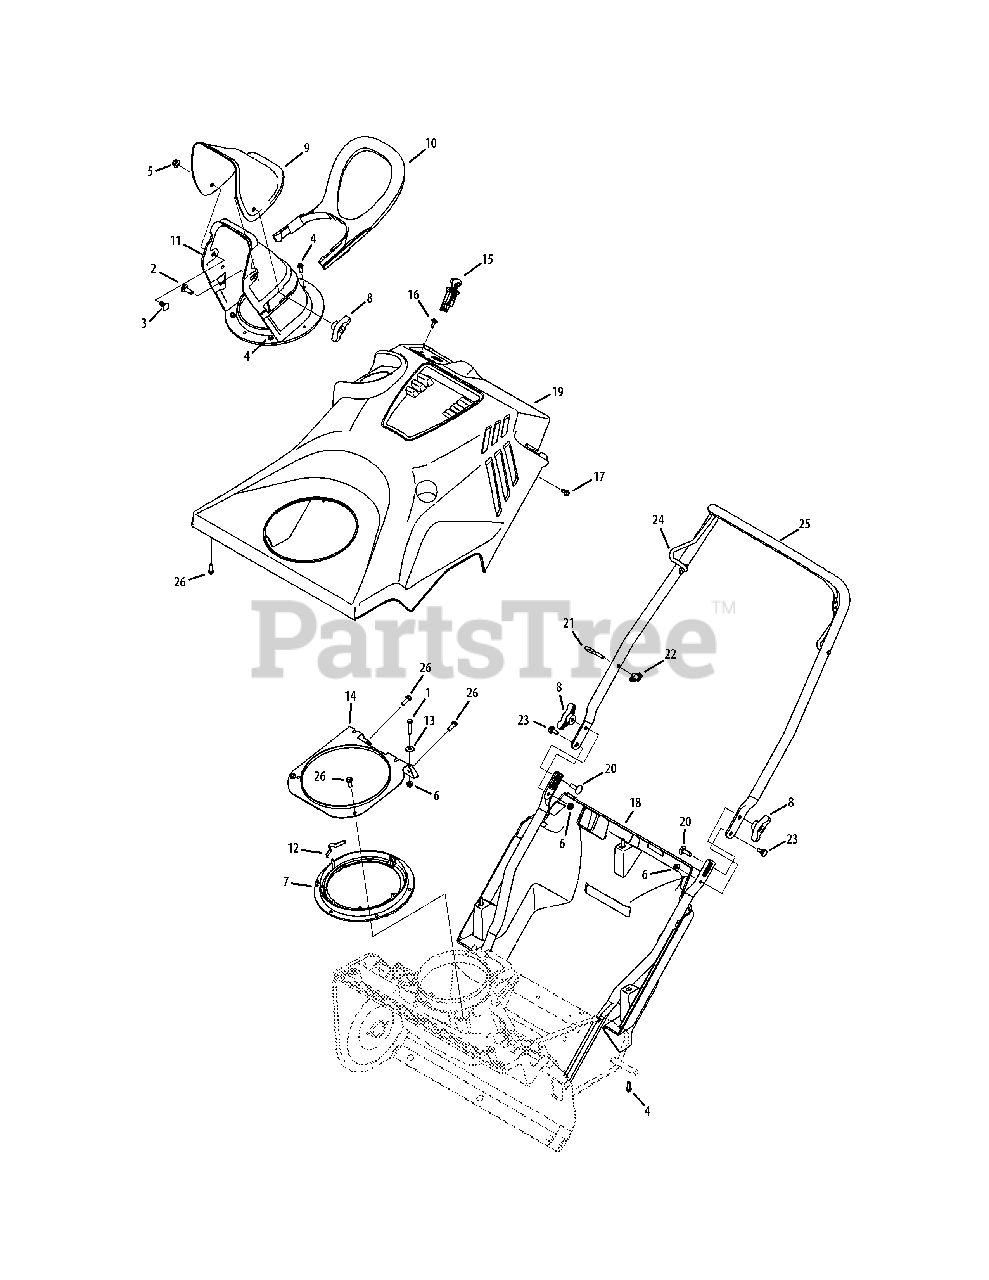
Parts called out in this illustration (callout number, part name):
1	Hex Screw, 1/4-20 x 1.25
2	Carriage Bolt, 5/16-18 x 1.00
3	Carriage Bolt, 5/16-18 x .750
4	Hex Washer Screw, 1/4 x .750
5	Flange Lock Nut, 5/16-18
6	Flange Lock Nut, 1/4-20
7	Bevel Gear
8	Wing Knob, 5/16-18
9	Upper Chute
10	Chute Handle
11	Lower Chute
12	Chute Adjustment Spring
13	Flat Washer, .28 x .74 x .063
15	Ignition Switch Assembly
16	Hex Washer Screw, 10-16 x .625
17	Hex Washer Screw, 1/4-20 x .500
18	Bottom Cover
19	Top Cover
20	Carriage Screw, 5/16-18 x 1.00
21	Eye Bolt, 1/4-20
22	Handle Knob
23	Shoulder Screw, 1/4-20 x .375 x .148
24	Auger Bail
25	Upper Handle
26	Screw, Hi-Lo:1/4-15, 0.75
